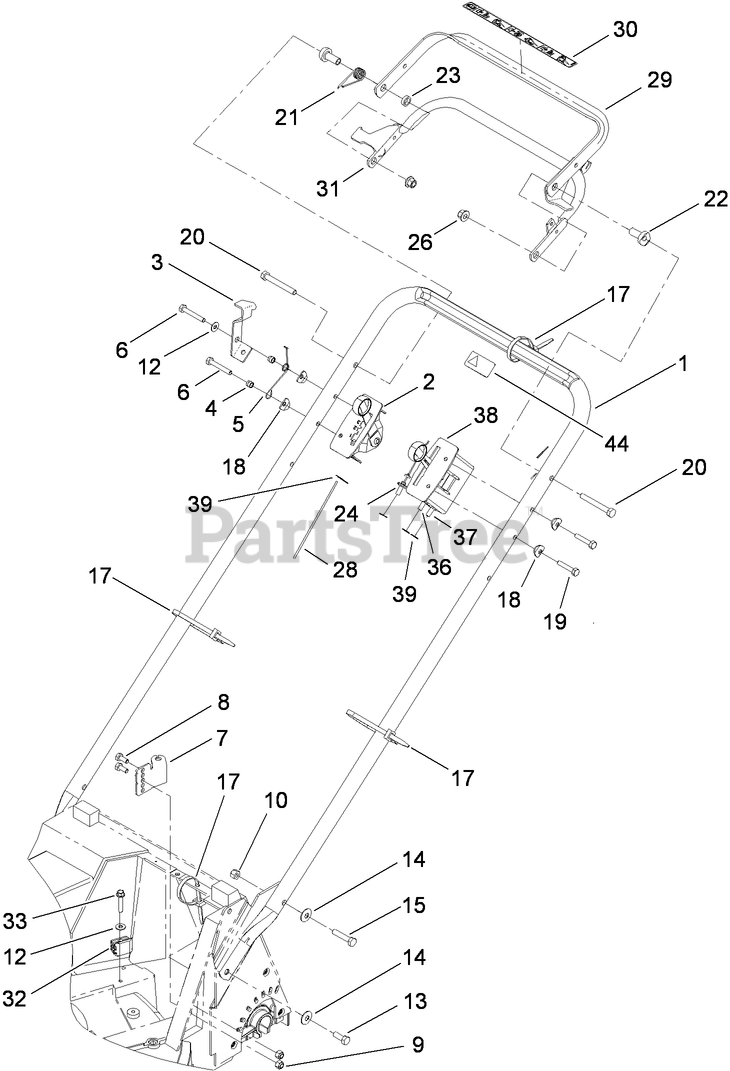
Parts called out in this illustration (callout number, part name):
1	HANDLE
2	CONTROL-SHIFT
3	LATCH-LEVER, BBC
4	SPACER-FLANGE
5	SPRING-TORSION, LATCH
6	SCREW-HH
7	ANCHOR-CABLE
8	SCREW-HH
9	NUT-LOCK, NI
10	NUT-LOCK, NI
12	WASHER-FLAT
13	SCREW-HH
14	WASHER-BELLEVILLE
15	SCREW-HH
17	TIE-CABLE
18	WASHER
19	SCREW-HH
20	SCREW-HH
21	Spring-Torsion
22	SPACER-SUPPORT
23	SPACER
24	CABLE-BBC
26	NUT-LOCK, NI
28	CABLE-SHIFT
29	TRACTION BAIL ASM
30	DECAL-CONTROL
31	BBC BAIL ASM
32	ANCHOR-CABLE, UPPER
33	SCREW-HWH
36	CABLE-TRACTION
37	THROTTLE CABLE ASM
38	CONTROL HEAD
39	E-RING
44	DECAL-PROTECTION, EAR
